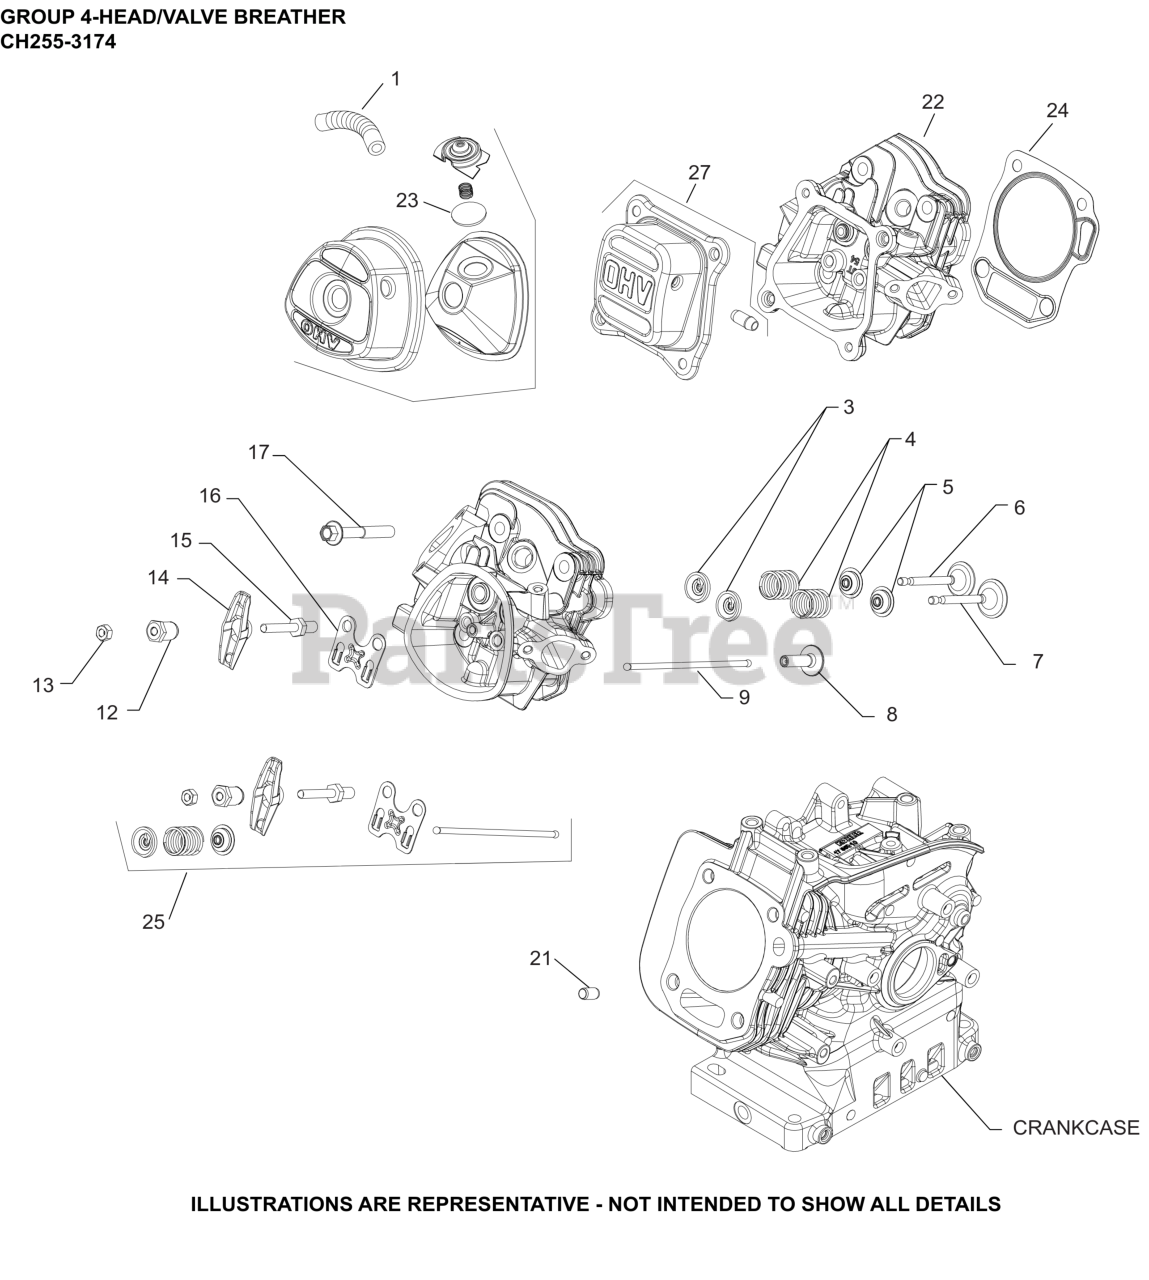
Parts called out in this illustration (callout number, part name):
1	TUBE, BREATHER
3	RETAINER, VALVE SPRING
4	SPRING, VALVE
5	SEAL, VALVE
6	VALVE, EXHAUST
7	VALVE, INTAKE
9	ROD, PUSH-(#1841101S)
12	PIVOT, ROCKER ARM
13	NUT, HEX JAM
14	ARM, ROCKER
15	STUD, ROCKER ARM-USE 14 072 22-S
16	PLATE, PUSHROD GUIDE
17	SCREW, HEX FLANGE CYL HEAD
21	PIN, DOWEL (8mm)
21	DOWEL, CYLINDER HEAD
22	CYLINDER HEAD
23	REED, BREATHER
24	GASKET, CYLINDER HEAD
25	KIT, VALVE TRAIN
27	COVER, VALVE ASSEMBLY
